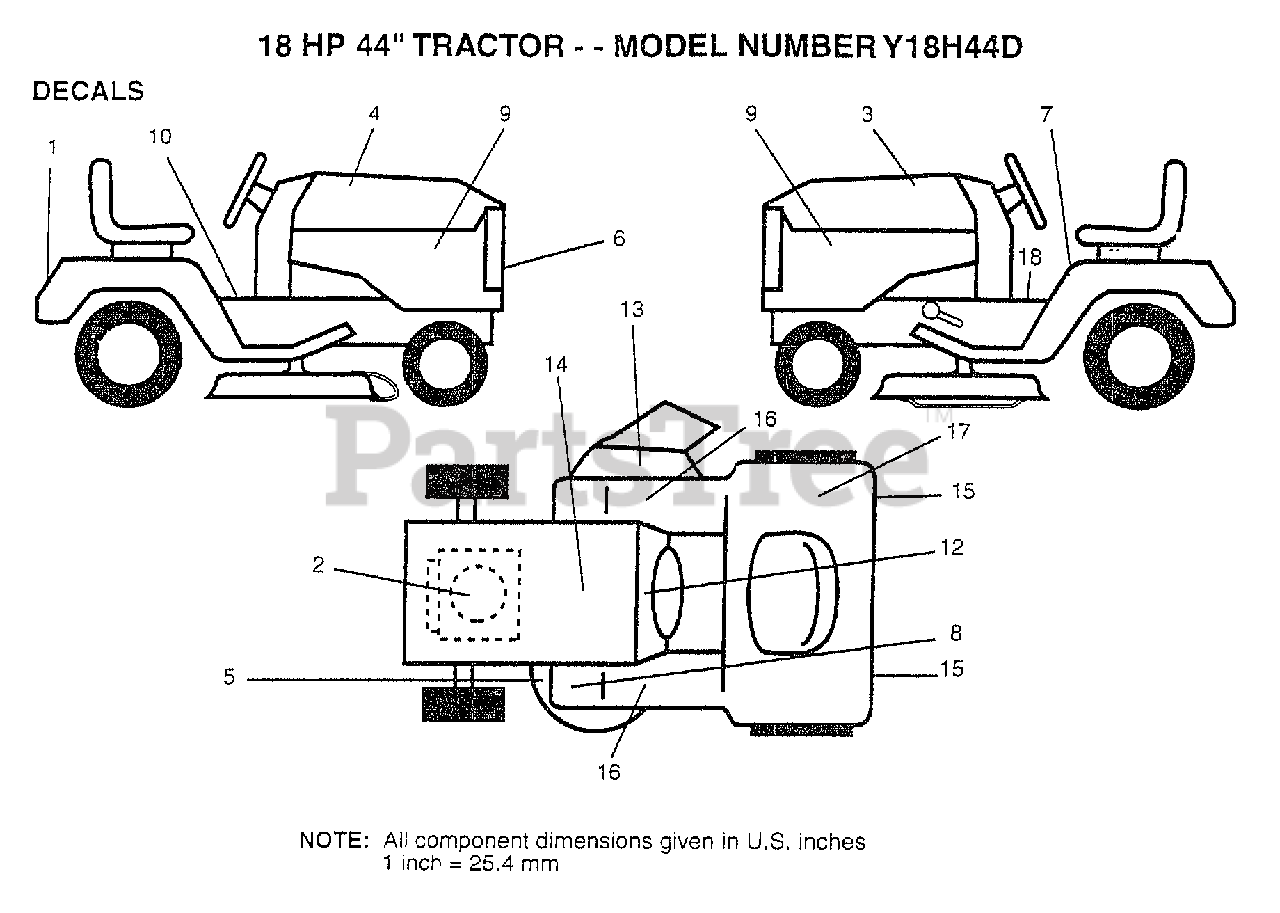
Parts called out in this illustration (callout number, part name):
2	"DECAL,HP ENGINE"
3	DECAL HOOD LH
5	"DECAL.V.BELT.44"""
6	DECAL.GRILL.YARDP
7	DECAL CAUTION
8	DECAL T
9	DECAL.PANEL.SIDE
10	DECAL BRAK PARK
12	DECAL.DASH.INSTR.
13	"DECAL, WARNING"
14	DECAL
15	REFLECTOR-TAIL YT
16	FOOTREST PAD
18	DECAL SADL HYDRO
